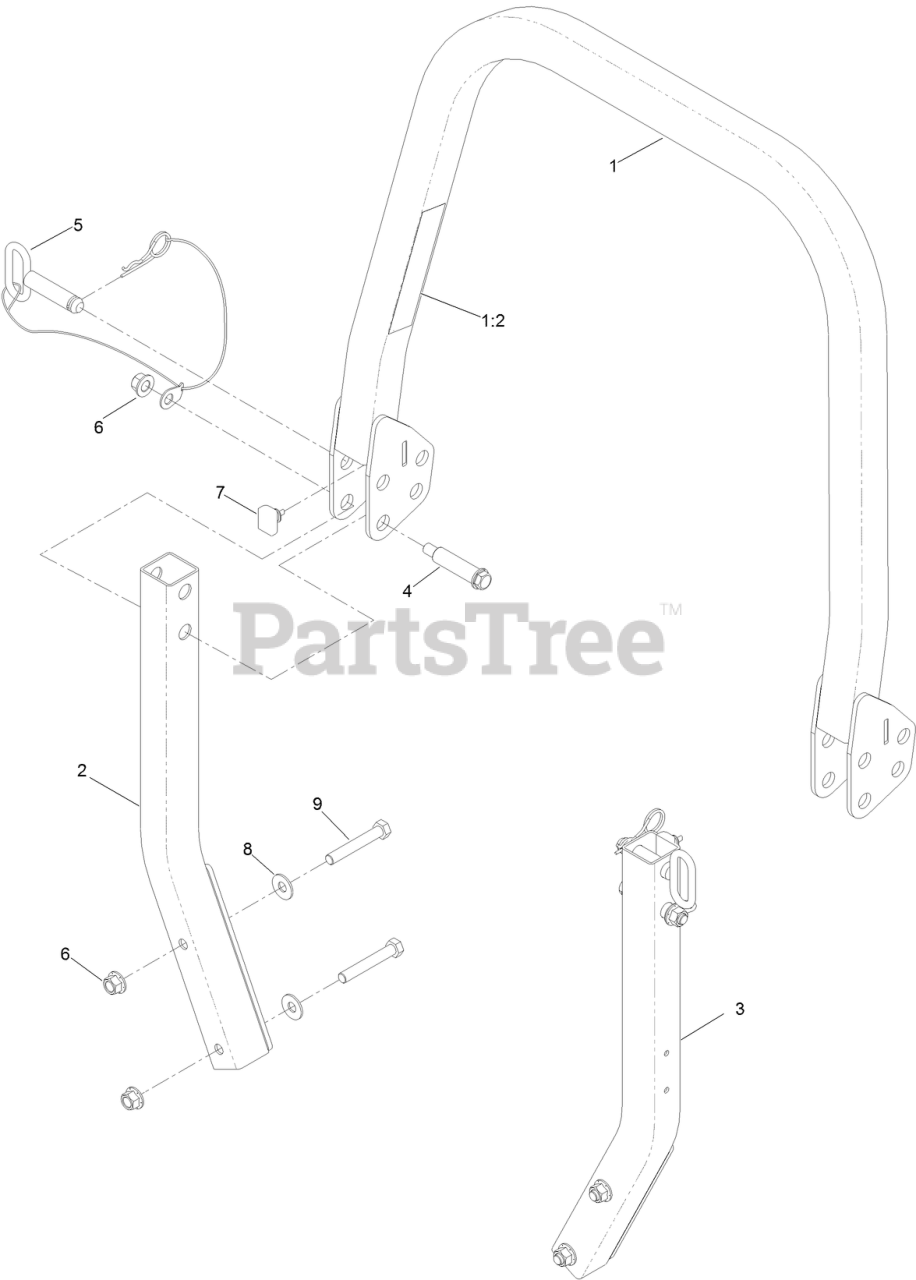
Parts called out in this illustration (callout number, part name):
1	UPPER ROPS ASM
1:2	DECAL-WARNING
2	RH LOWER ROPS ASM
3	LH LOWER ROPS ASM
4	BOLT-SHOULDER
5	PIN-FOLD, ROPS
6	NUT-LOCK
7	BUMPER-ROPS
8	WASHER-SPRING
9	SCREW-HH
